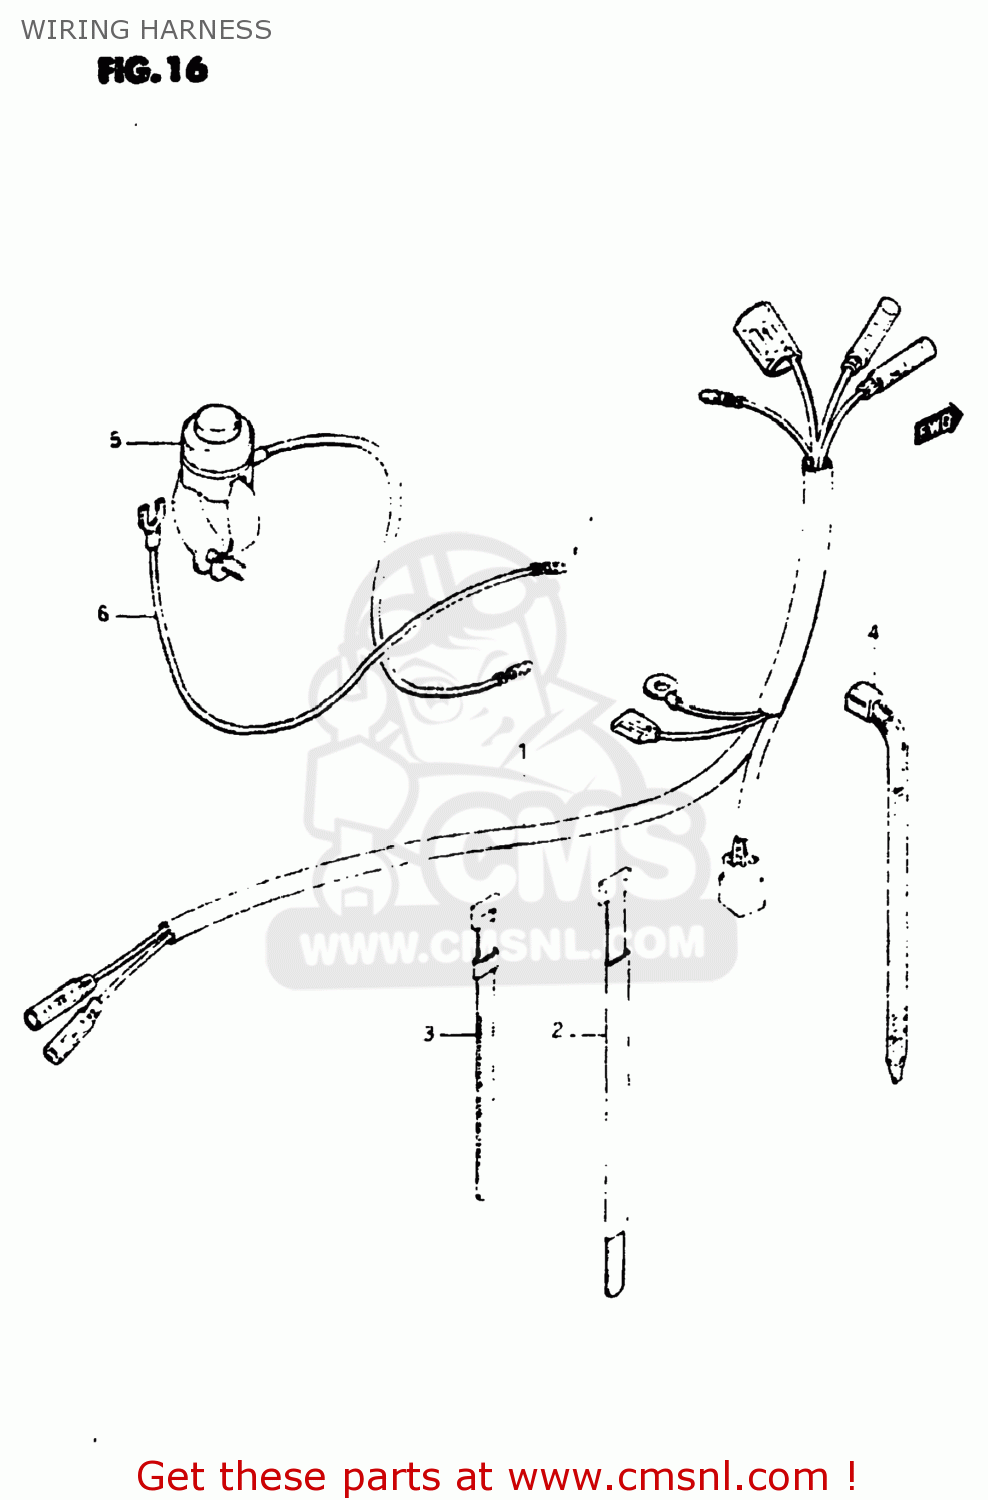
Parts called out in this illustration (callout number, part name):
1	HARNESS,WIRING
2	CLAMP
3	CLAMP(L:120)
4	CLAMP(L:165)
5	SWITCH ASSEMBLY
6	WIRE,LEAD
